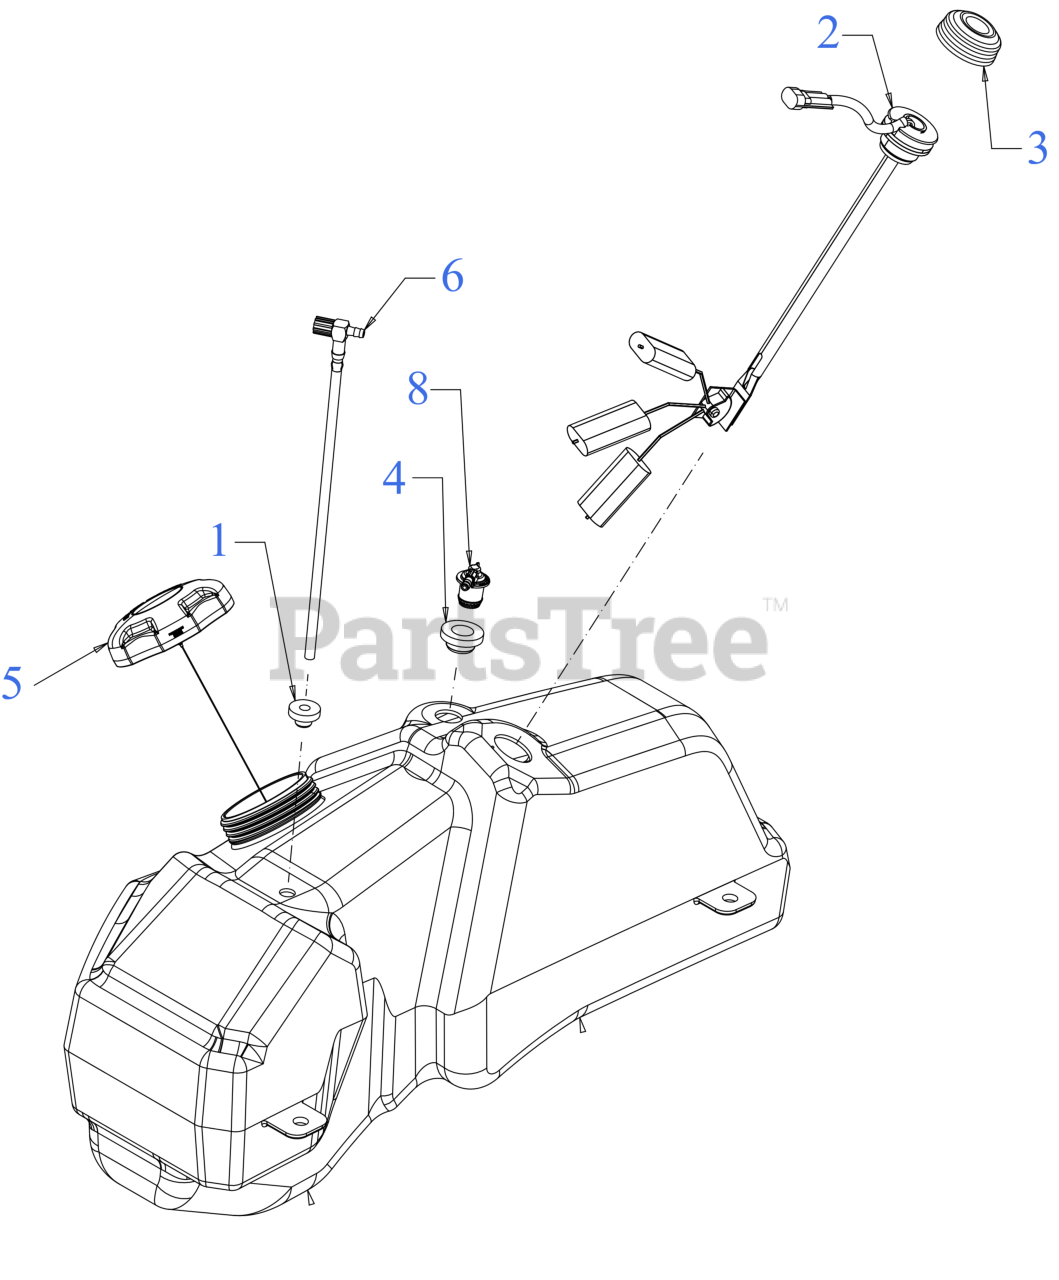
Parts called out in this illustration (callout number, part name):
1	GROMMET-FUEL TANK
2	FUEL LEVEL SENSOR
3	CASTER AXLE CAP
4	GROMMET .755 x .955 x .55
5	FUEL CAP - 3.50" ONE WAY VENT
6	FUEL PICKUP VALVE
8	FUEL VENT FITTING
